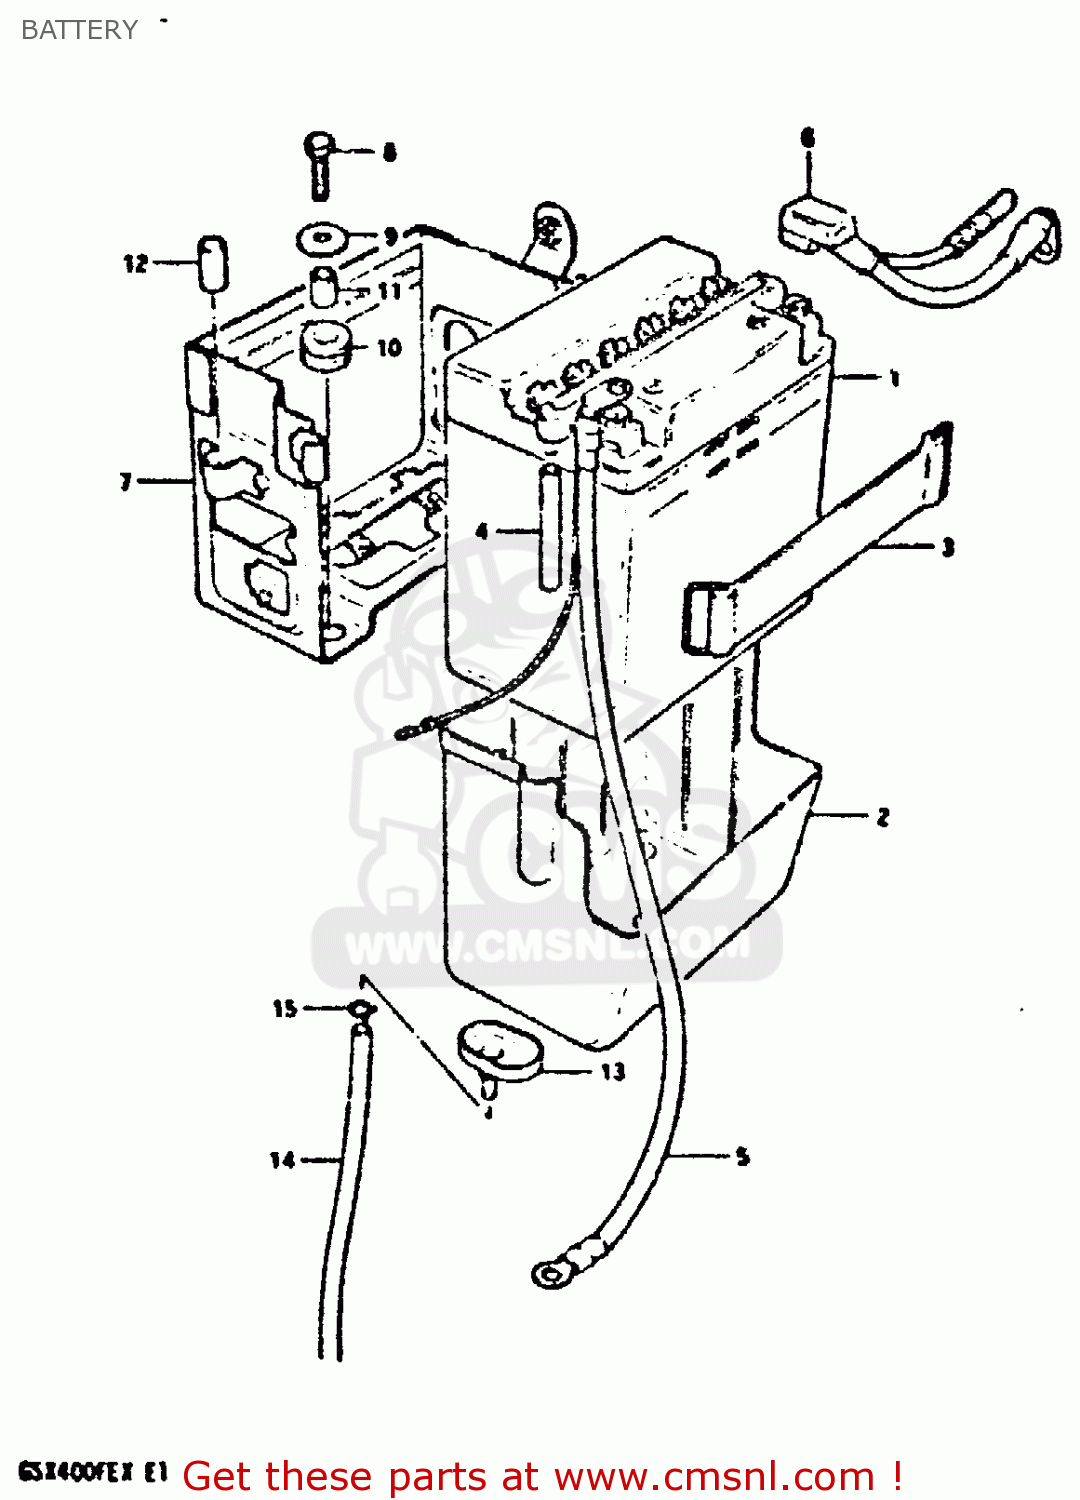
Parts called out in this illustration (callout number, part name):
1	BATTERY (12V, 12AH)
2	CASE,BATTERY
3	BAND
4	HOSE, EXHAUST (L:45)
5	LEAD WIRE, (-)
6	LEAD WIRE, (+)
7	HOLDER, BATTERY
8	BOLT, UPPER
9	WASHER
10	CUSHION
11	SPACER(6.1X9X7.5)
12	CUSHION
13	FUNNEL,BATTERY EXHAUST
14	HOSE,BATTERY EXHAUST
15	CLIP
